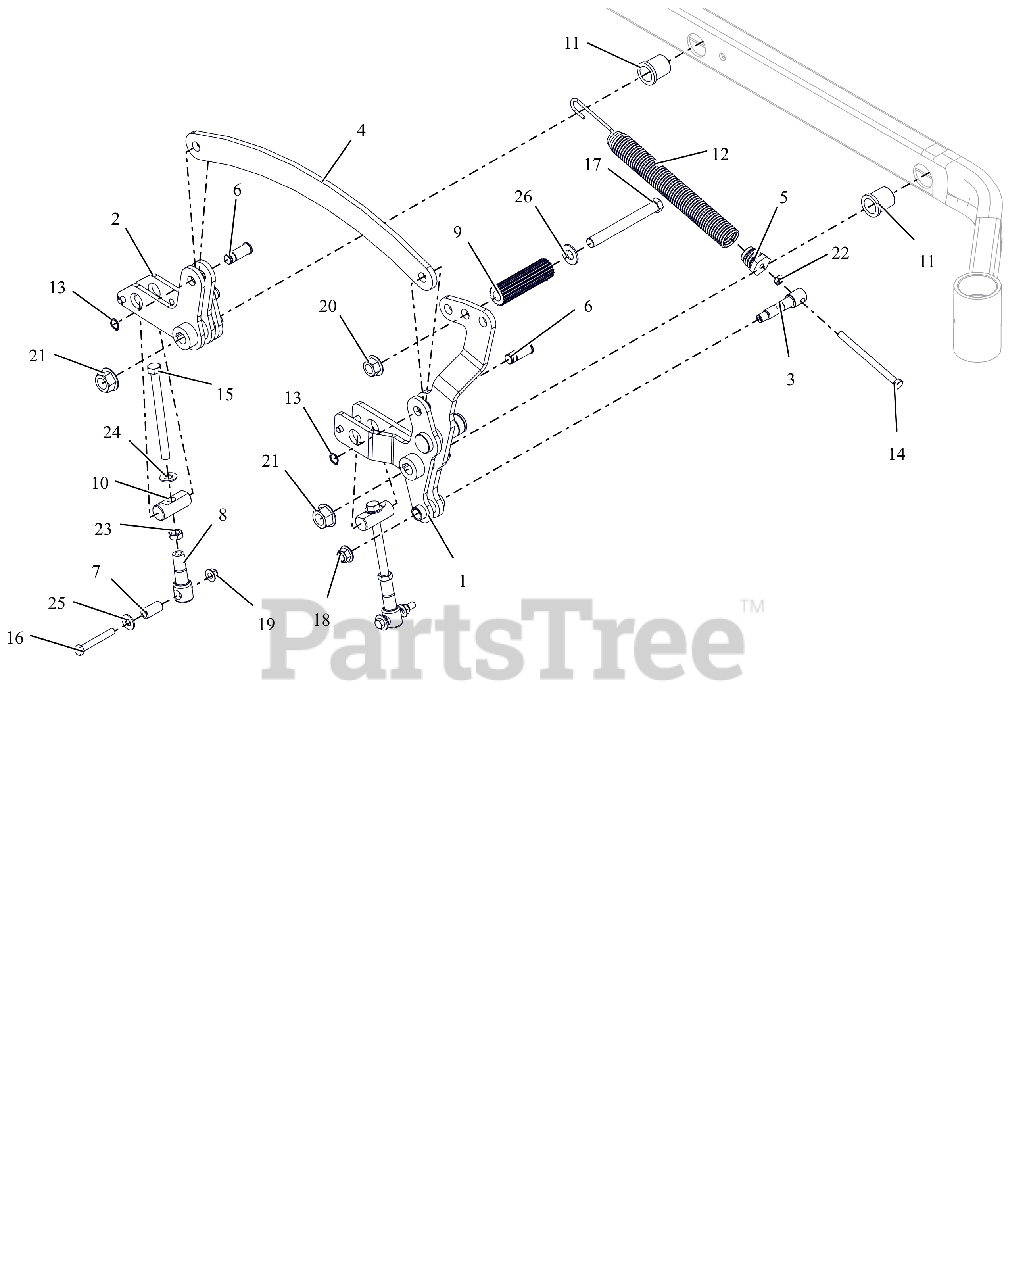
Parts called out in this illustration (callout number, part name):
1	FRONT RH DECK LIFT ARM WMT-LF
2	REAR RH DECK LIFT ARM WLDMT-LF
3	TRUNION, DECK LIFT SPRING
4	LINK, CONNECTING
5	PLUG, SPRING
6	PIN, CLEVIS .625 SNAP RING
7	SPACER, DECK LEVELING
8	LINK, DECK LIFT FORMED
9	ROD, FOOT PEDAL (BLACK)
10	PIN, DECK LIFT
11	BSHG-FLG 1.00X1.25X1.50X1.50
12	SPRING, DECK LIFT
13	RG-RTNG-EXT .625X.050
14	BLT, HEX .38-16X5.00F G5 ZCC
15	BLT, HEX .50-13X6.00S G5 ZCC
16	BLT, HEX .38-16X2.75 G8 ZCC
17	BLT, HEX .62-11X5.50 G5 FBP
18	NUT,NYL-FLG .50-13 GF ZCC
19	NUT,NYL-FLG .38-16 GF ZCC
20	NUT,FLG-TOP LK .625-11 FBP
21	NUT,FLG-TOP LK .625-11 FBP
22	NUT-JAM .375-16 G2 ZCC
23	NUT-JAM .500-13 G2 ZCC
24	WSHR, FLT .557X1.040X.102 ZCC
25	WSHR,FLT .438X1.00X.083 ZCC
26	WSHRFLT 5/8SAE CARBHARD FBP
